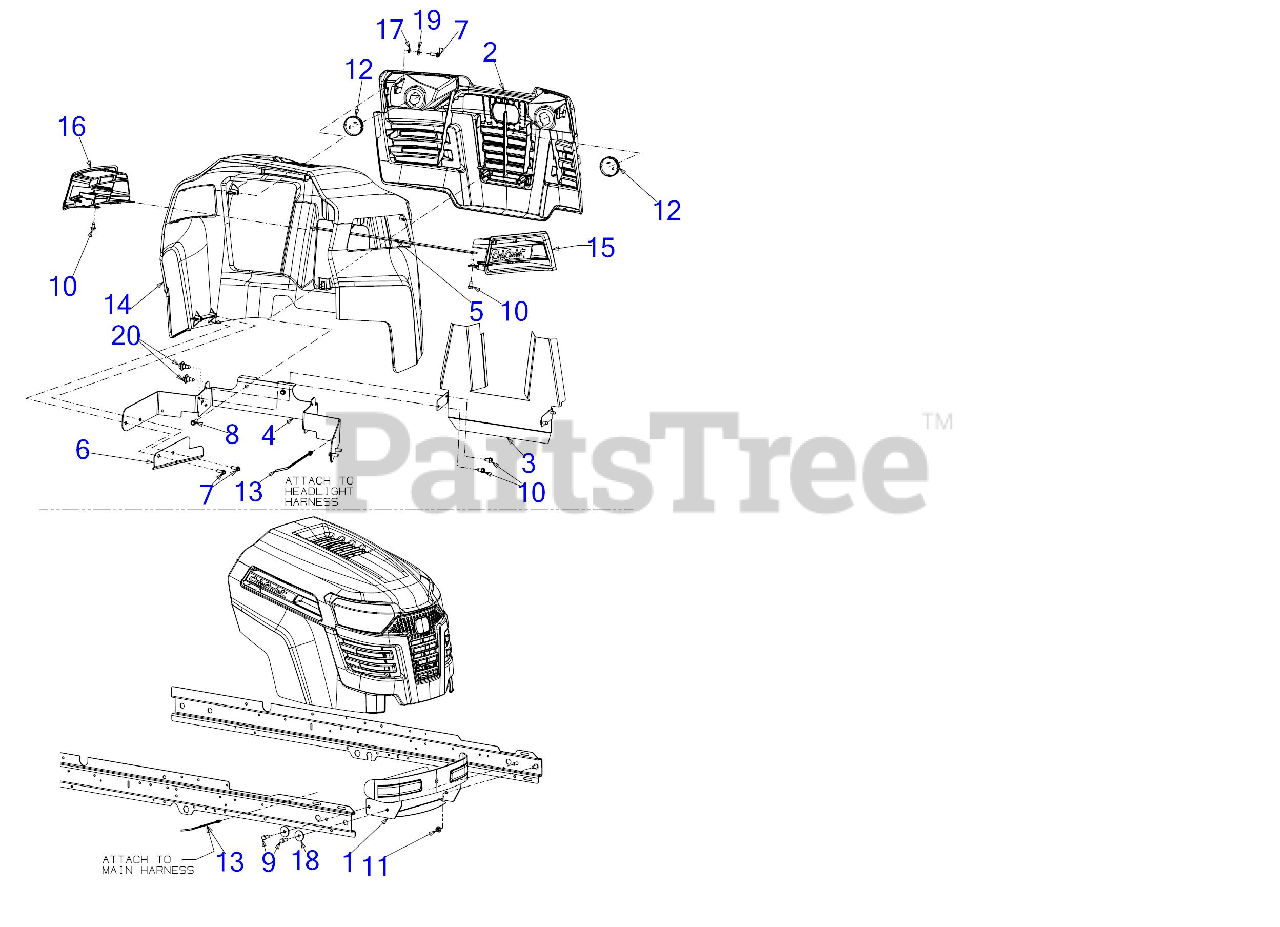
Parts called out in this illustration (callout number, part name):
2	GRILLE ASSEMBLY
3	DEFLECTOR SHIELD
4	HOOD PIVOT BRACKET
5	HOOD CROSS BRACE
6	HEAT EXHAUST SHIELD
7	SCREW 1/4 x .750
8	SCREW 5/16-14 x 1
9	SCREW 3/8-16 x 1 GR5
10	SCREW 1/4-20 X.500
12	HEADLIGHT ASSEMBLY
13	PUSH MOUNT TIE
14	HOOD (CUB YELLOW)
15	HOOD SCOOP (RH)
16	HOOD SCOOP (LH)
17	LOCK WASHER 1/4
18	FLAT WASHER .390x1.500x.134
19	FLAT WASHER .271:.630:.065
20	SHOULDER SCREW .43X.29X5/16-18 TT
